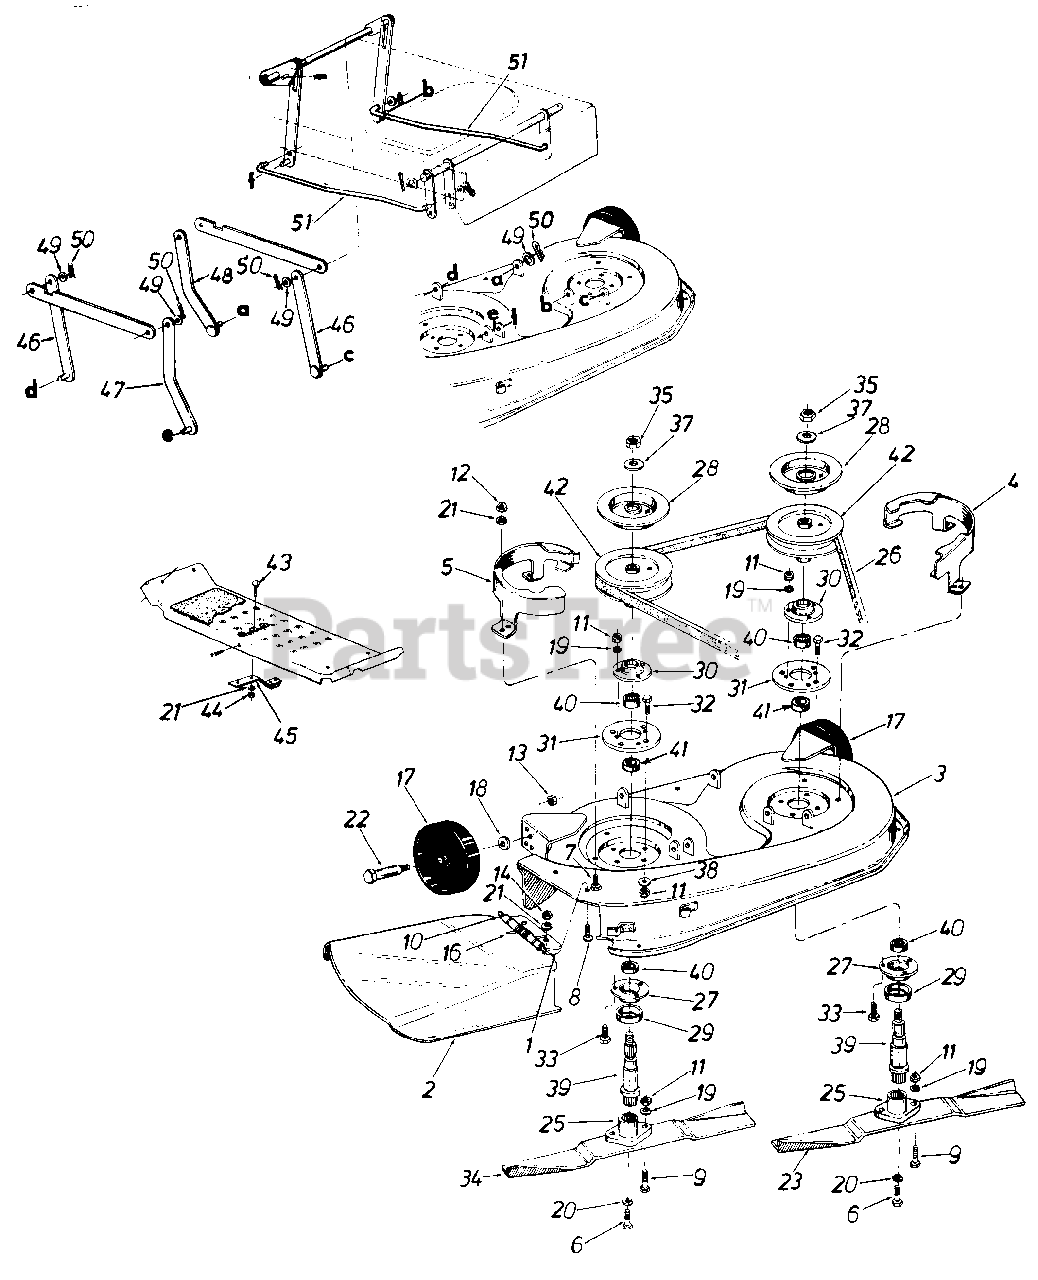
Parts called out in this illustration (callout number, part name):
1	Chute Bracket
2	Chute Deflector
3	38" Deep Deck Ass'y.
6	Hex Bolt 3/8-24 x 1.00"
7	Hex Bolt 1/4-28 x .62"
8	Truss Mach. Scr. 1/4-20 x .75"
9	Hex Scr Special 5/16-24 x 1 .O"
10	Hinge Pin
11	Hex Nut 5/16-24 Thd.
12	Hex Nut 1/4-28 Thd.
13	Hex Top L-Nut 3/8-16 Thd.
14	Hex Jam Nut 1/4-20 Thd.
16	Torsion Spring
17	Deck Wheel-5"
18	Bell-Wash. .40" I.D. x .88" O.D.
19	L-Wash. 5/16" I.D.
20	L-Wash. 3/8" I.D.-H.D.
21	L-Wash. 1/4" I.D.
22	Shld. Bolt .498" Dia. x 1.53"
23	High-Lift Blade-L.H.
25	Blade Adapter
26	5L V-Belt
27	Bearing Housing 1.85" I.D.
28	Brake Disc
29	Bearing Shield
30	Open Brg. Housing 1.85" I.D.
31	Spindle Meeting Plate
32	Hex Bolt 5/16-24 x .75"
33	Hex Bolt Special 5/16-24 x 1 .O"
34	High-Lift Blade-R.H.
35	Hex Jam Nut 5/8-18 Thd.
37	L-Wash. 518" I.D.
38	Bell-Wash. .345" I.D. x .88" O.D.
39	Blade Spindle
40	Ball Brg. .787" I.D. x 1.85" O.D.
41	Spacer 1.0" O.D. x .790" I.D. x .350"
42	5" Dia. Pulley
43	Carr. Bolt 1/4-20 x .62"
44	Hex Nut 1/4-20 Thd.
45	Blade Brake Ass'y
46	Link Deck Hanger Ass'y.
47	Link Deck Hanger Ass'y.
50	Inter. Cotter Pin .50" Dia.
51	Stabilizer Rod
